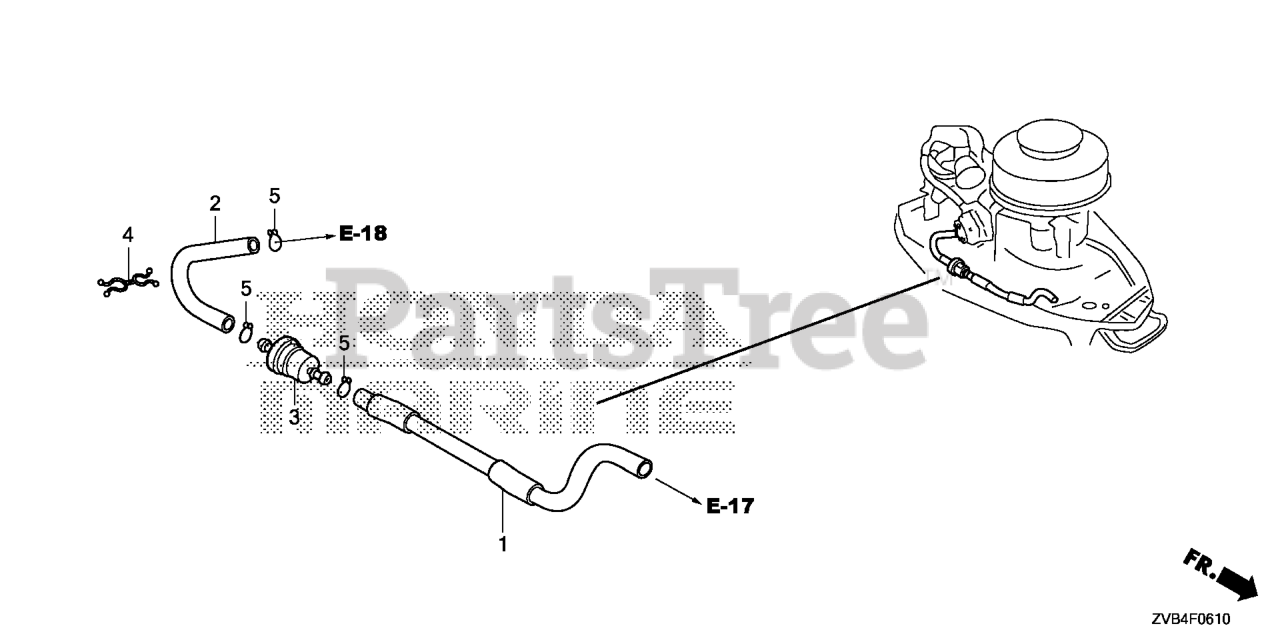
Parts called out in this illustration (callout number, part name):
1	TUBE C, FUEL
2	TUBE D, FUEL
3	FILTER, FUEL
4	CLIP, WIRE HARNESS
5	CLIP, TUBE (B1 10)
